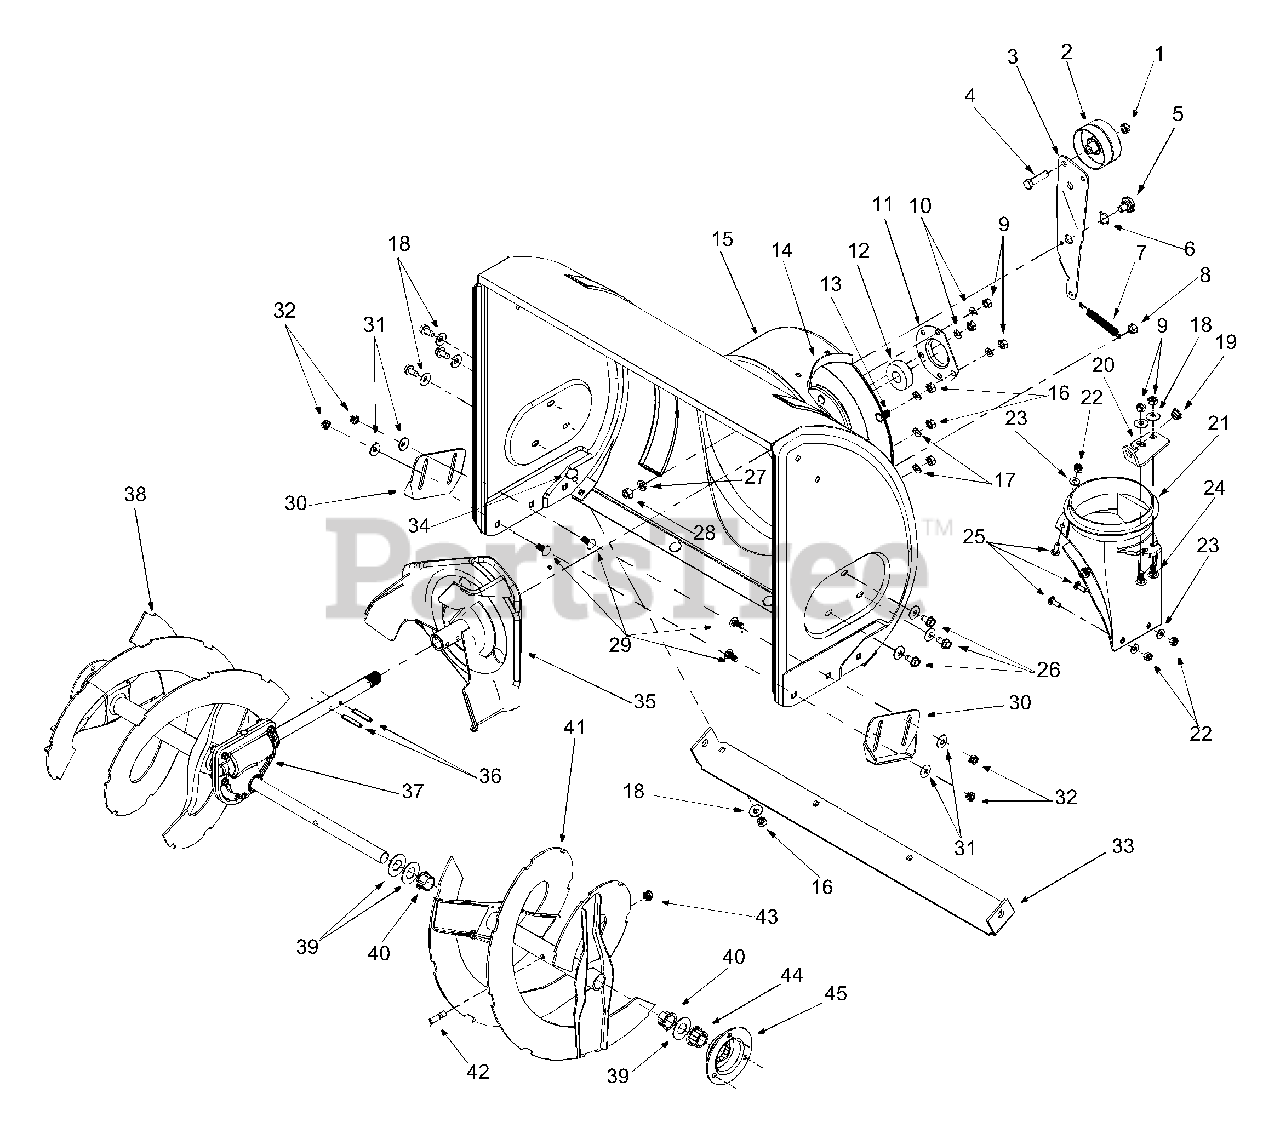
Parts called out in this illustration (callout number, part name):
1	Lock Jam Nut 3/8-24
2	Flat Idler
4	Hex Cap Screw 3/8-24 x 1.50
5	Shoulder Screw
6	Wave Washer
7	Extension Spring
8	Hex Nut 5/16-18
9	Hex Nut 5/16-18
10	Lock Washer 5/16
11	Bearing Housing
12	Ball Bearing
13	Carriage Bolt 5/16-18
17	Lock Washer 5/16
18	Bell Washer
19	Bushing
21	Chute Adapter
22	Hex Lock Nut 1/4-20
23	Flat Washer
24	Carriage Bolt
25	Carriage Screw 1/4-20 x .75
26	Hex Washer Screw 5/16-18
27	Lock Washer 3/8
28	Hex Nut 3/8-16
29	Carriage Bolt 5/16-18 x .75
31	Bell Washer
32	Hex Nut 5/16-18
34	Carriage Bolt 5/16-18 x .62
37	26" Gear Assembly
39	Flat Washer
40	Flange Bushing
43	Lock Nut 5/16-18
44	Hex Flange Bearing
